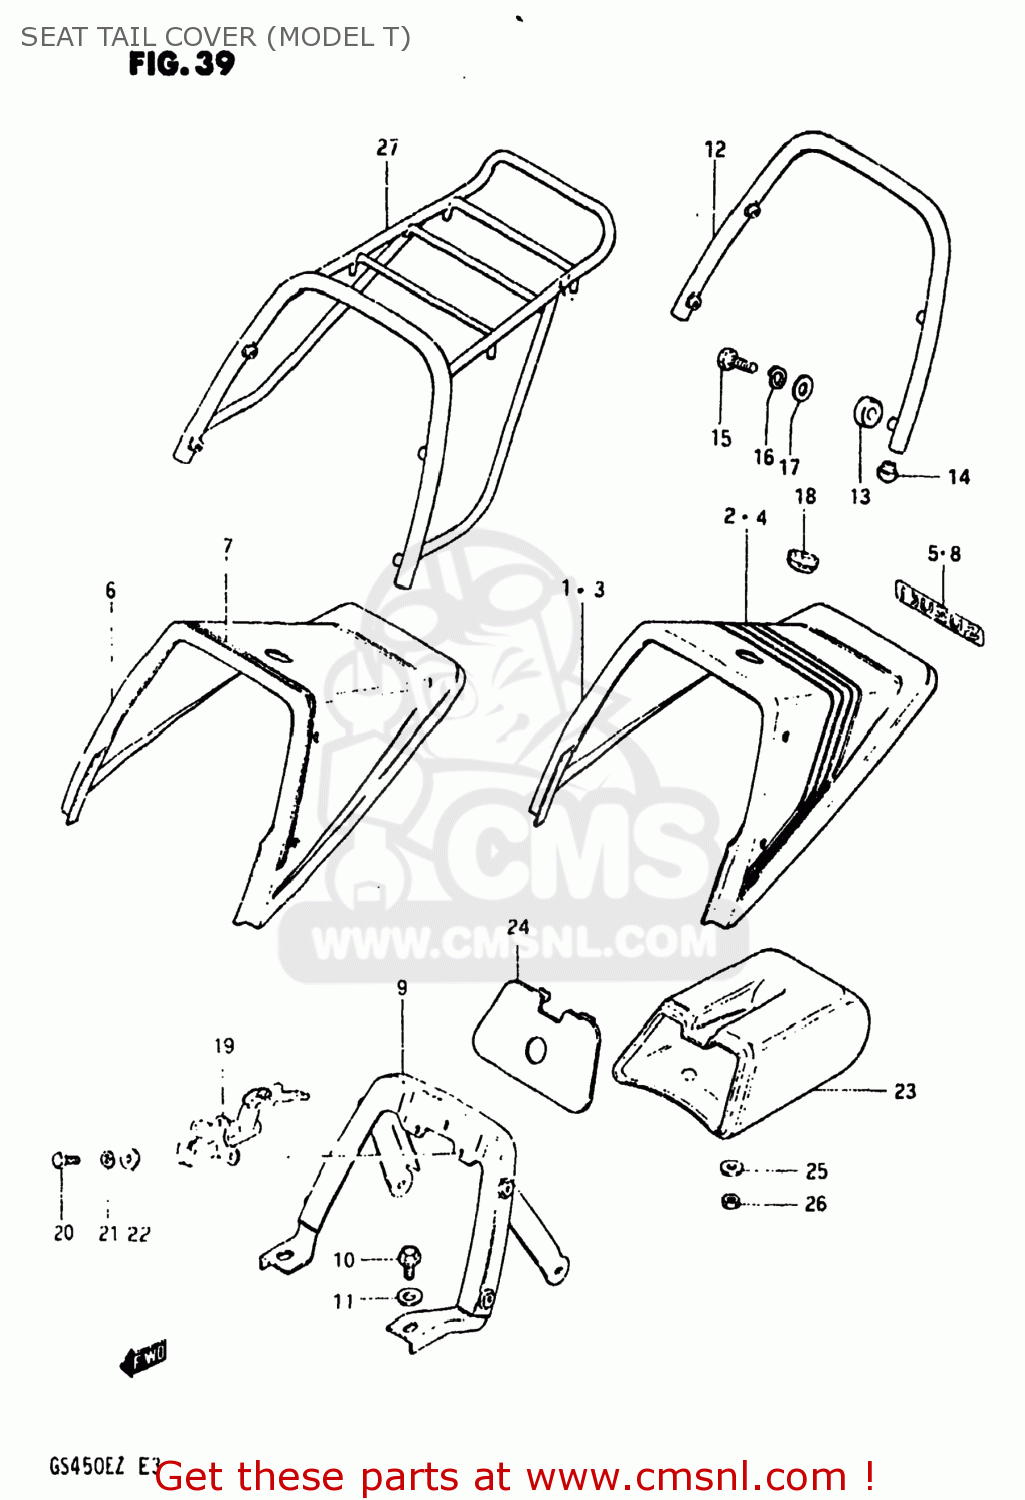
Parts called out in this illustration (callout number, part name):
1	COVER,SEAT TAIL
2	TAPE SET,SEAT TAIL COVER
3	COVER,SEAT TAIL
4	TAPE SET,SEAT TAIL COVER
5	EMBLEM (GOLD/BLACK)
6	COVER,SEAT TAIL
7	TAPE SET,SEAT TAIL COVER
8	EMBLEM,SEAT TAIL COVER
9	BRACKET, SEAT TAIL COVER
10	BOLT
11	WASHER (8.7X22X2)
12	HANDLE,PILLION RIDER
13	CUSHION
14	END,SHEET HANDLE
15	BOLT (8X30)
16	LOCK WASHER
17	WASHER
18	GROMMET,SEAT LOCK HOLE
19	LOCK SET
20	BOLT
21	LOCK WASHER
22	WASHER
23	BOX, SEAT TAIL
24	LID,SEAT TAIL BOX
25	WASHER
26	NUT 6MM
27	CARRIER
